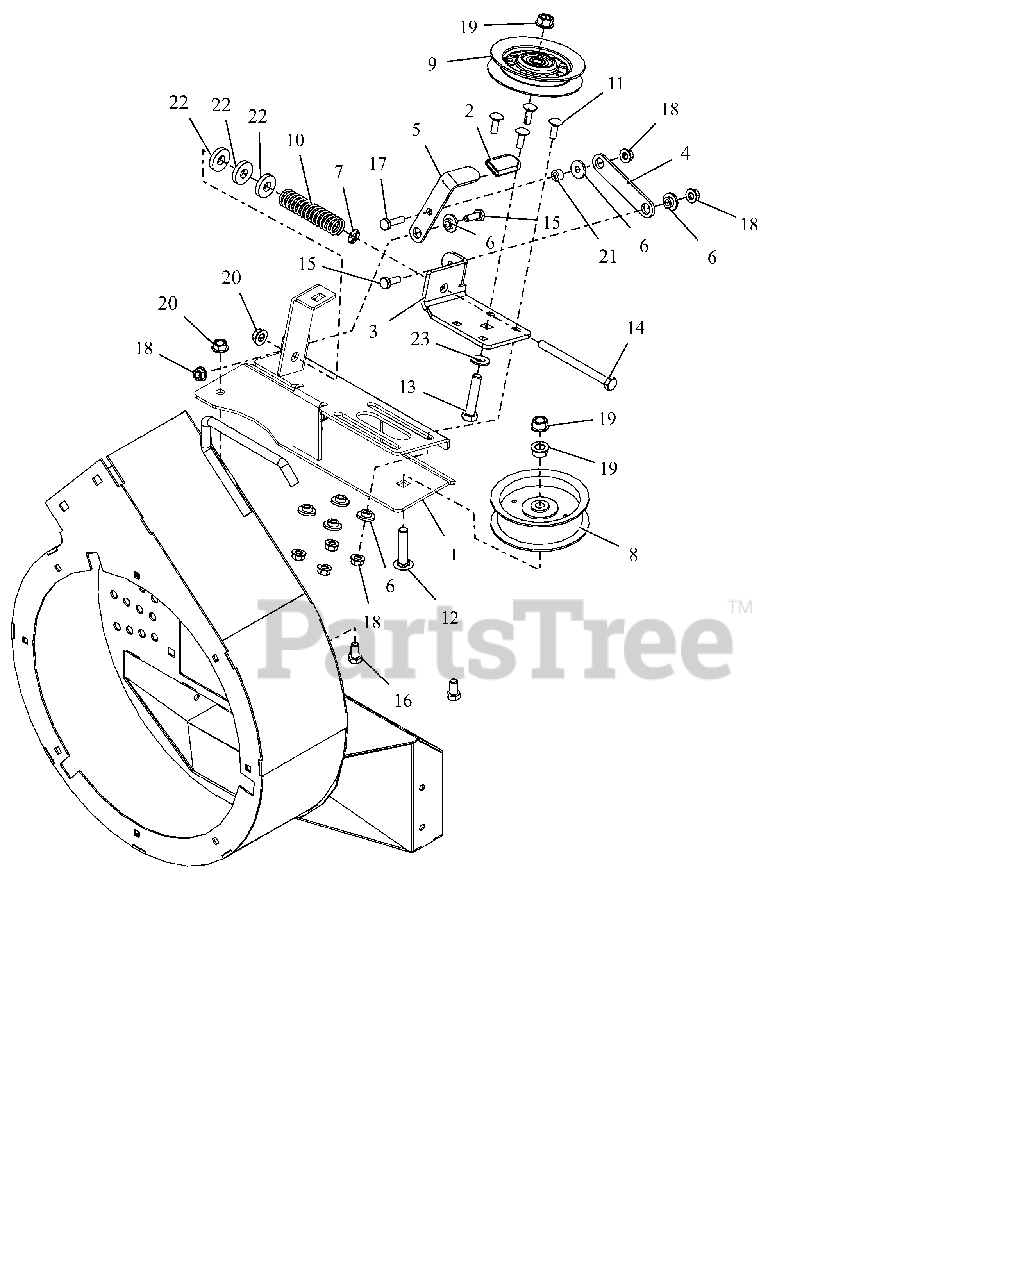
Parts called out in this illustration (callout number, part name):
1	WELDMENT, IDLER MOUNT -2015
2	GRIP, SEAT LEVER, GREY
3	BRACKET, ADJ. PULLEY IDLER
4	LINK, TENSIONER
5	HANDLE, TENSIONER
6	BSHG-FLG .265X.437X.250X.750
7	NUT-PUSH .312
8	IDLER, FLG .38ID X 3.50
9	V-IDLER, 4.00X.38
10	SG-COMP .092X.77X3.13 WLD 36
11	@BLT-RDHDSQNK .25-20X.75 G5YZ
12	BLT-RHDSSQNK .38-16X1.75 G5YZ
13	@BLT-HEX .38-16X1.75 GR5 YWZC
14	@BLT-HEX .31-18X4.00 GR5 YWZC
15	@BLT-HEX .25-20X.75 GR5 YWZC
16	BLT-HEX .31-18X.63 GR5 YWZC
17	@BLT-HEX .25-20X1.00 GR5 YWZC
18	@NUT-LK-TOP-FLG .25-20 YWZC
19	@NUT-LK-TOP-FLG .38-16 YWZC
20	@NUT-LK-TOP-FLG .31-18 YWZC
21	BUSHING, .26 ID X .44 OD X .26
22	WSHR-FL-STL .406X1.00X.188 YWZ
23	@WSHR-FL-STL.406X.812X.065 YWZ
